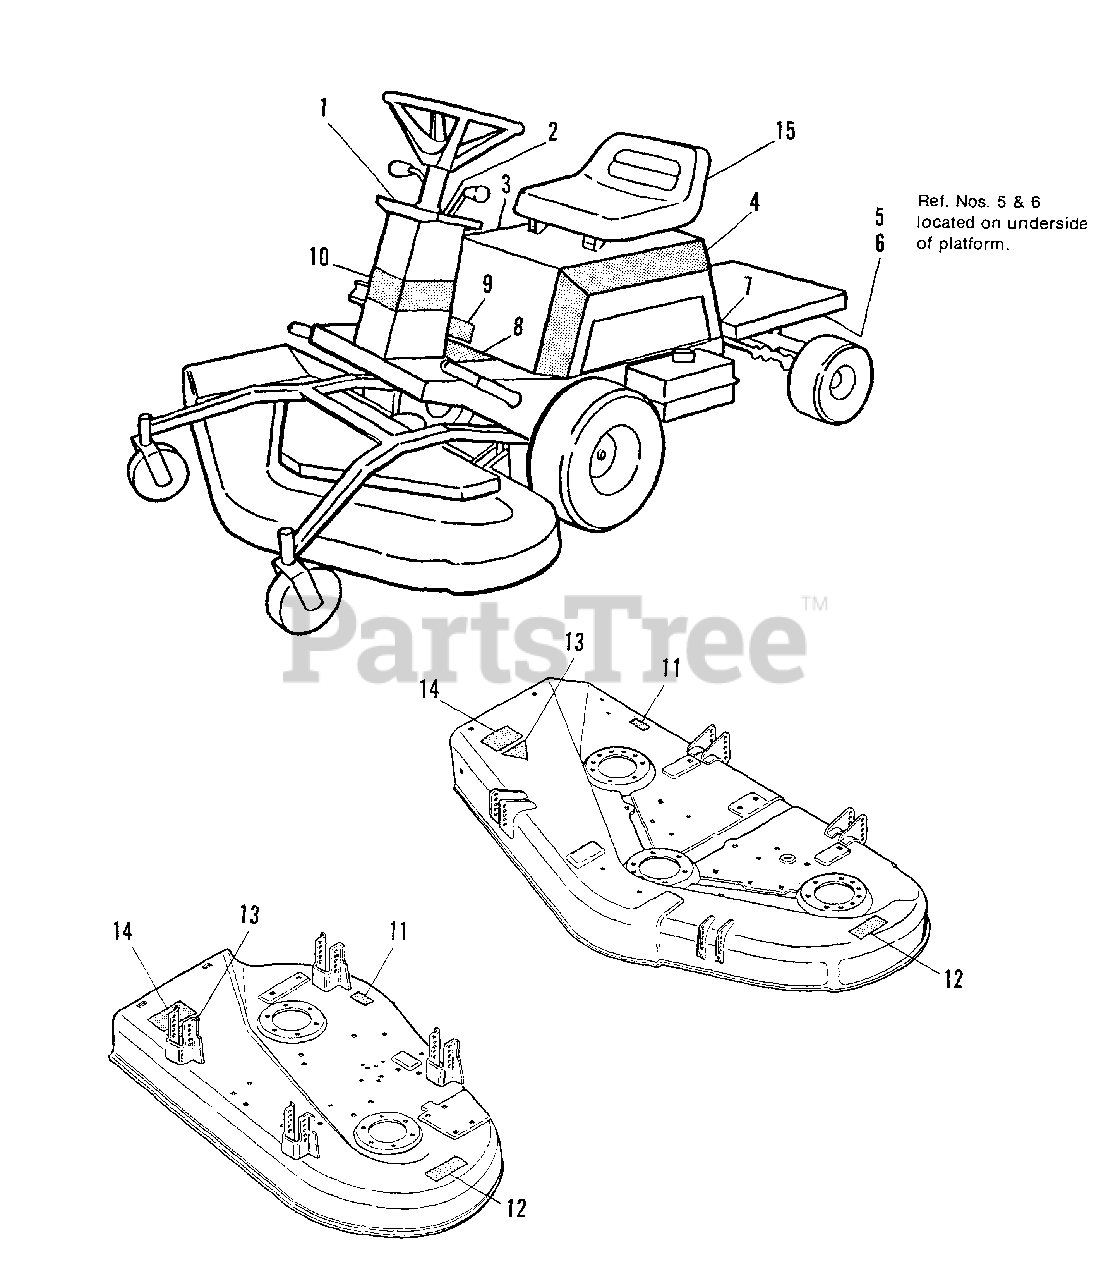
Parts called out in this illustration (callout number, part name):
1	DECAL, Shift Pattern
2	DECAL, Instrument Panel
3	DECAL, Side, R.H. (1691198 & 1691330 only)
3	DECAL, Side, R.H. (1691457 & 1691458 only)
4	DECAL, Side, L.H. (1691198 & 1691330 only)
4	DECAL, Side, L.H. (1691457 & 1691458 only)
5	DECAL, Drive Belts
6	DECAL, Stability
7	I.D. PLATE
8	DECAL, Caution & Controls
9	DECAL, Model No. 12 HP
9	DECAL, Model No. 8 HP
10	DECAL, Steering Column
11	I.D. PLATE
12	DECAL, Danger
13	DECAL, OPEI
14	DECAL, Danger
15	DECAL, Simplicity
